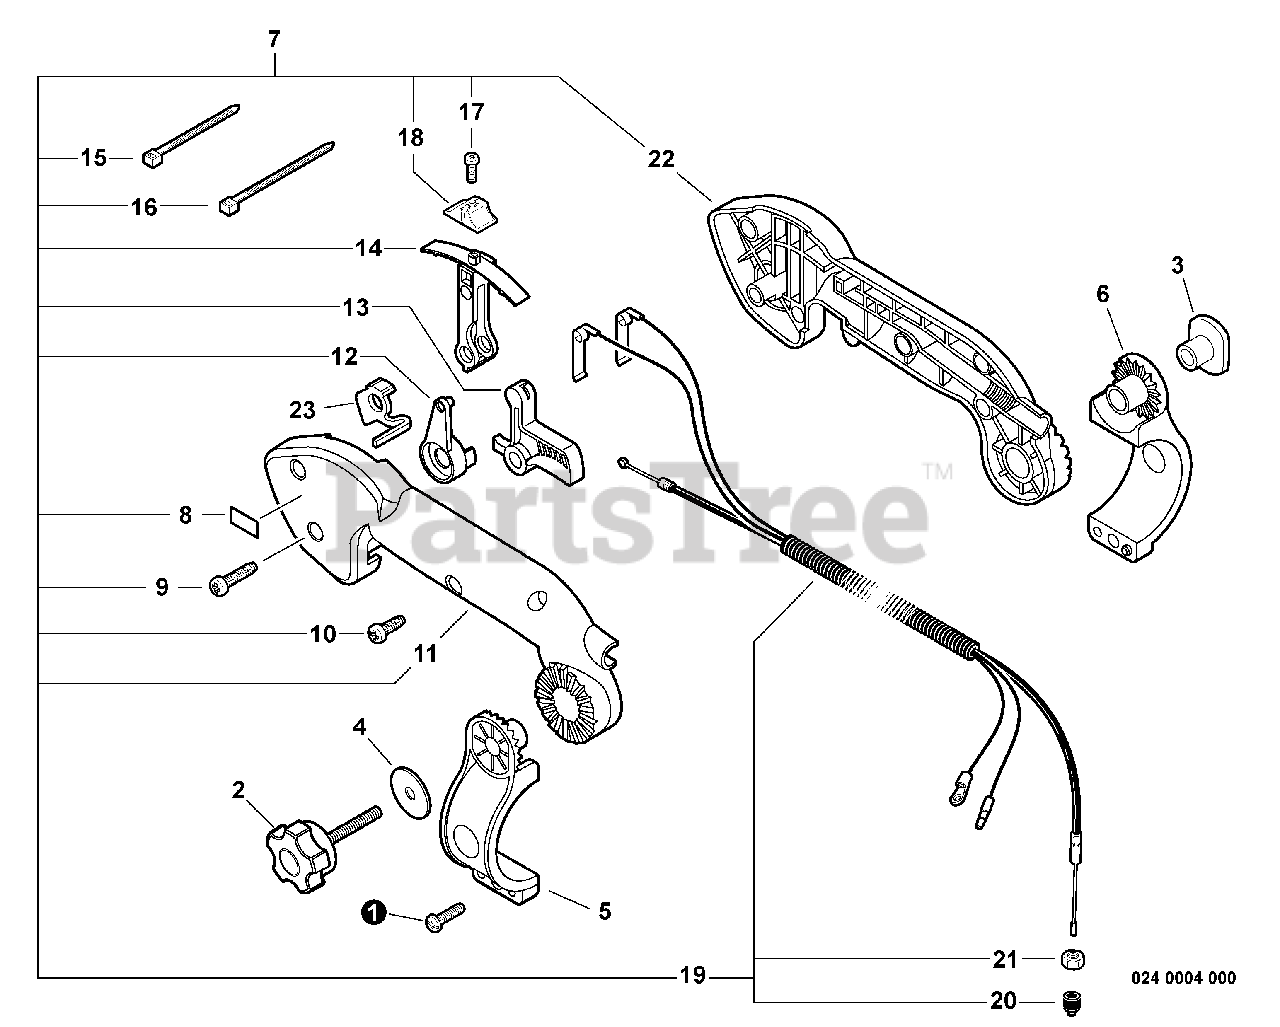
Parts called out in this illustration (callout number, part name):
1	SCREW - 5X20 -- TAPPING
2	THUMBSCREW
4	WASHER - 6
5	BRACKET, HANDLE - LEFT
6	BRACKET, HANDLE - RIGHT
7	CRUISE CONTROL KIT
8	LABEL - IDLE
9	SCREW - 5
10	SCREW - 5X20
11	HANDLE, FRONT - LEFT
12	LEVER, THROTTLE
13	TRIGGER, THROTTLE
14	LEVER, THROTTLE CONTROL
15	TIE, CABLE - SMALL
16	TIE, CABLE - LARGE
17	SCREW - 3X14
18	KNOB, THROTTLE CONTROL
19	CONTROL CABLE ASSY
20	CAP, DUST
21	LOCKNUT - 6
22	HANDLE, FRONT - RIGHT
23	GUARD, CONTACT
